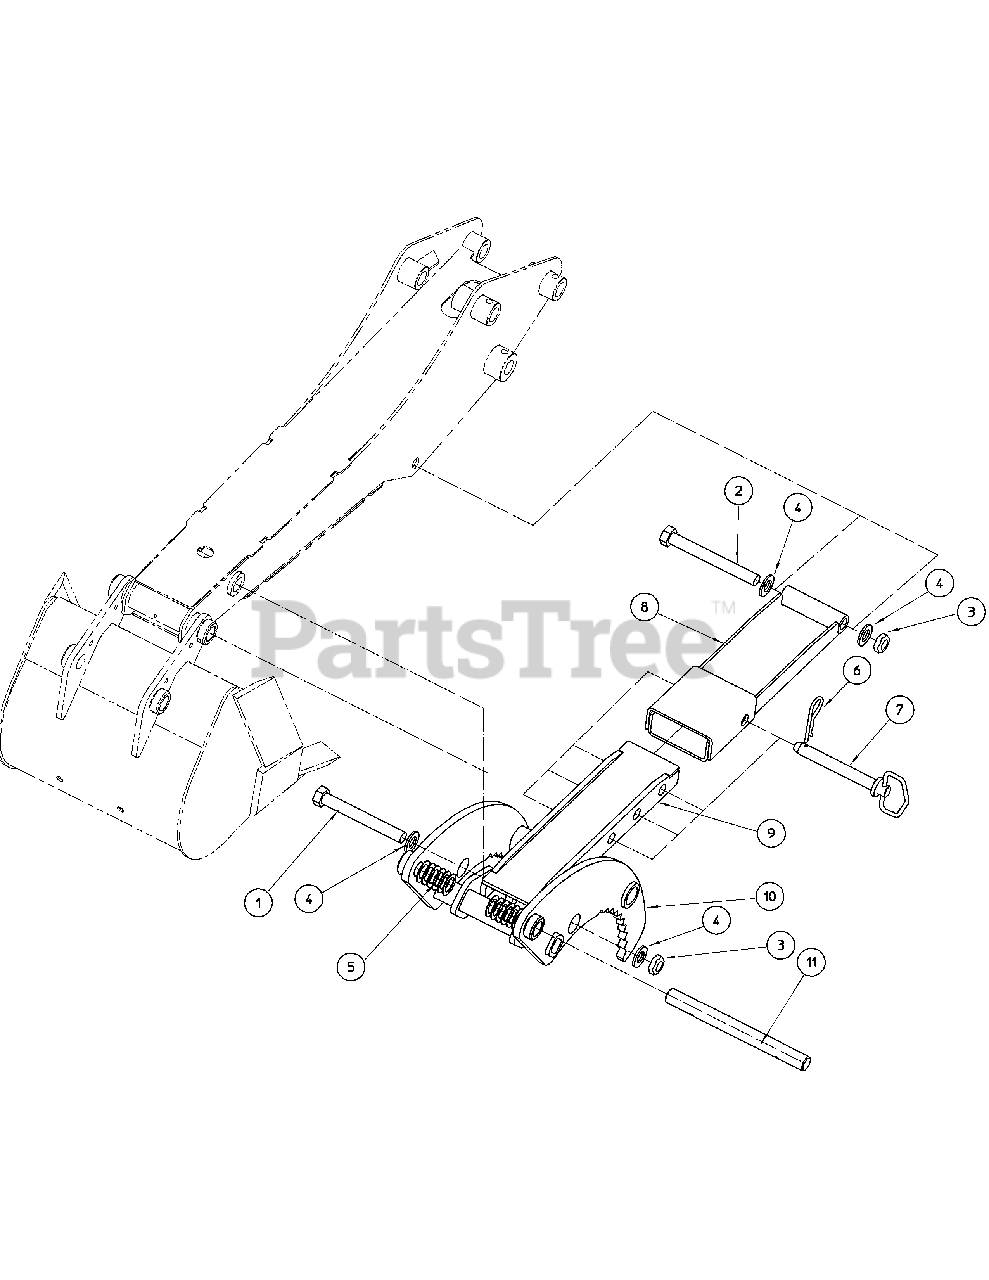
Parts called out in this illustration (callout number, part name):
1	Hex Head Cap Screw, 3/4-16 x 6.00 Gr 5
2	Hex Head Cap Screw, 3/4-16 x 6.50 Gr 8
3	Nut, Hex 3/4-16 Jam
4	Flat Washer, 3/4 SAE
5	Machine Bushing 1 x 1-1/2 x 18G
6	Hair Pin Clip, #6
8	Upper Column Weldment
9	Lower Column Weldment
10	Mechanical Thumb Weldment
11	Bucket/Thumb Link Pin
